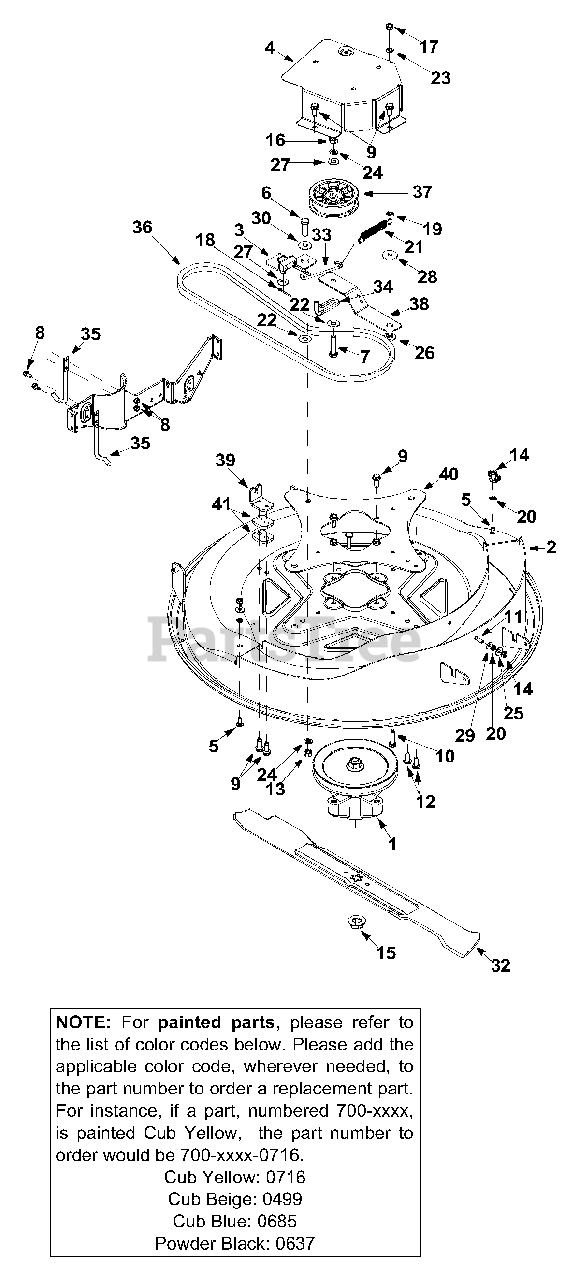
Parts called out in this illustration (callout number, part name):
1	Spindle Assembly
5	Carriage Screw 1/4-20 x .62"
6	Hex Bolt 3/8-24 x 1.25"
7	Hex Screw 3/8-16 x 1.75"
8	Self-Tapp. Screw 1/4-20 x .5"
9	Self-Tapp. Screw 5/16-18 x .75"
10	Hex Cap Scr. 5/16-24 x 1.25"
11	Carriage Screw
12	Torx Screw 5/16-18 x .75"
13	Hex Nut 3/8-24
14	Wing Nut
15	Flange Nut 5/8-18
16	Hex Nut 3/8-16
17	Hex Nut 5/16-24
18	Cotter Pin
19	Speed Nut
21	Extension Spring
22	Flat Washer 3/8 x 1.00 x .030"
23	Lock Washer 5/16
24	Lock Washer 3/8
26	Bushing
27	Flat Washer .406 x .875 x .059"
28	Flat Washer .330 x 1.25 x .120"
29	Flat Washer
30	Spacer
34	Belt Keeper
37	Flat Idler Pulley
38	Idler Bracket
39	Cable Bracket
